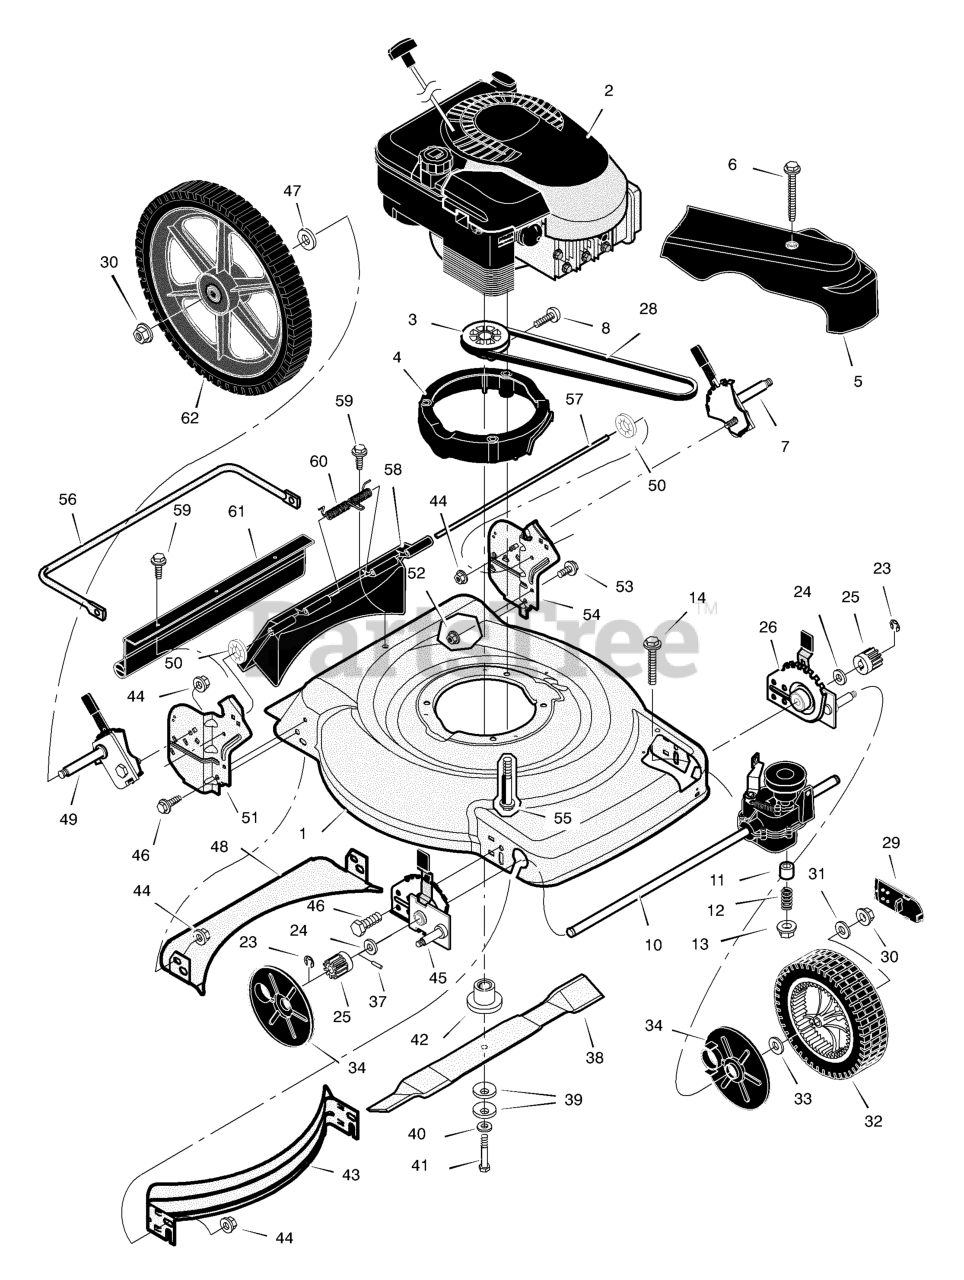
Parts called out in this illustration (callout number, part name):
1	Housing
2	Engine *
3	Pulley, Drive
4	Spacer, Engine
5	Cover, Belt (Black)
7	Adjuster, Left Rear Height
10	Transmission *
12	Spring, Compression
13	Nut
14	Bolt
25	Gear, Pinion
26	Adjuster, Left Front Height
29	Cap, Hub
30	Nut, Flange
31	Washer
32	Wheel & Tire, Front
34	Cover, Dust
37	Pin, Drive
39	Washer, Belleville
42	Adapter, Blade
43	Baffle, Front
44	Nut, Flange
45	Adjuster, Right Front Height
46	Bolt
48	Baffle, Rear
49	Adjuster, Right Rear Height
50	Retainer, Push
51	Bracket, Right Handle
52	Nut, Flange
53	Bolt
54	Bracket, Left Handle
55	Bolt, Engine
57	Rod, Pivot
58	Door, Rear (Black)
60	Spring
61	Guard, Rear
62	Wheel & Tire, Rear
